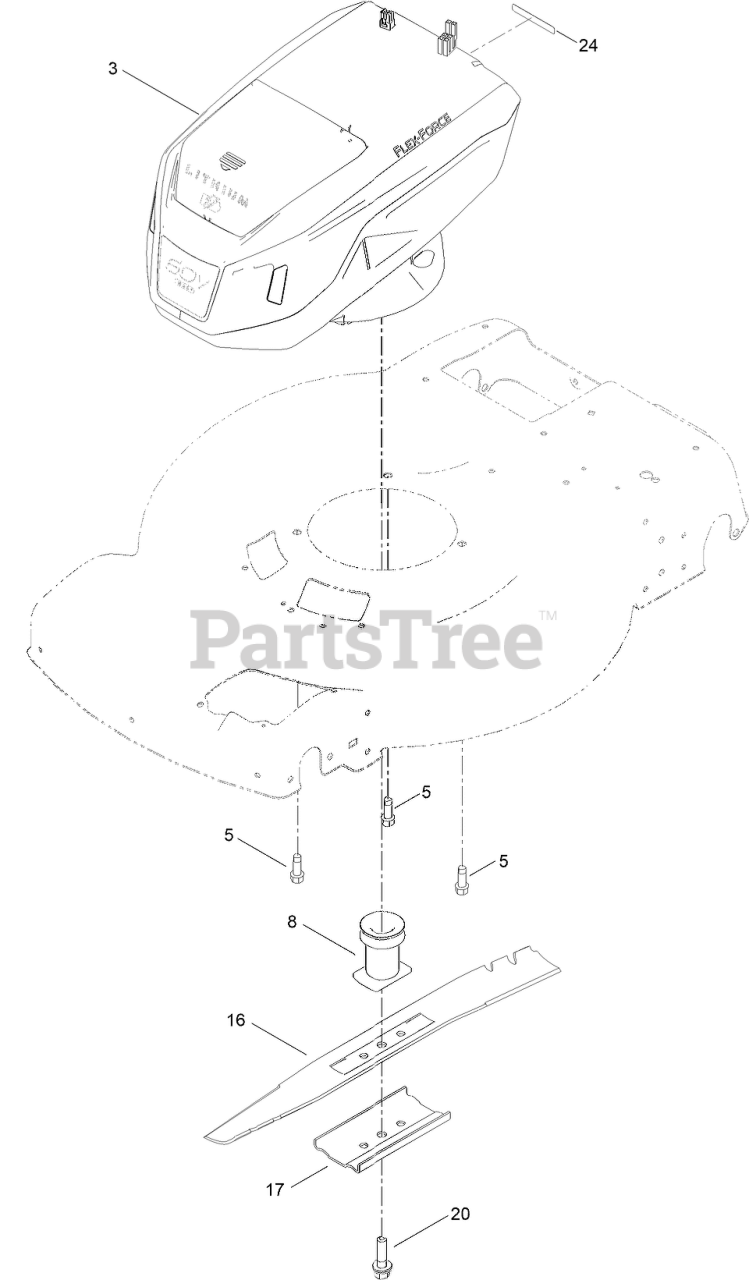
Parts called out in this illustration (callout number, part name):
3	MOTOR MODULE 60V
5	SCREW-THD FORM, HWH
8	DRIVER-BLADE
16	BLADE [BLACK]
17	SUPPORT-BLADE
20	BOLT-BLADE
24	DECAL-WARNING
